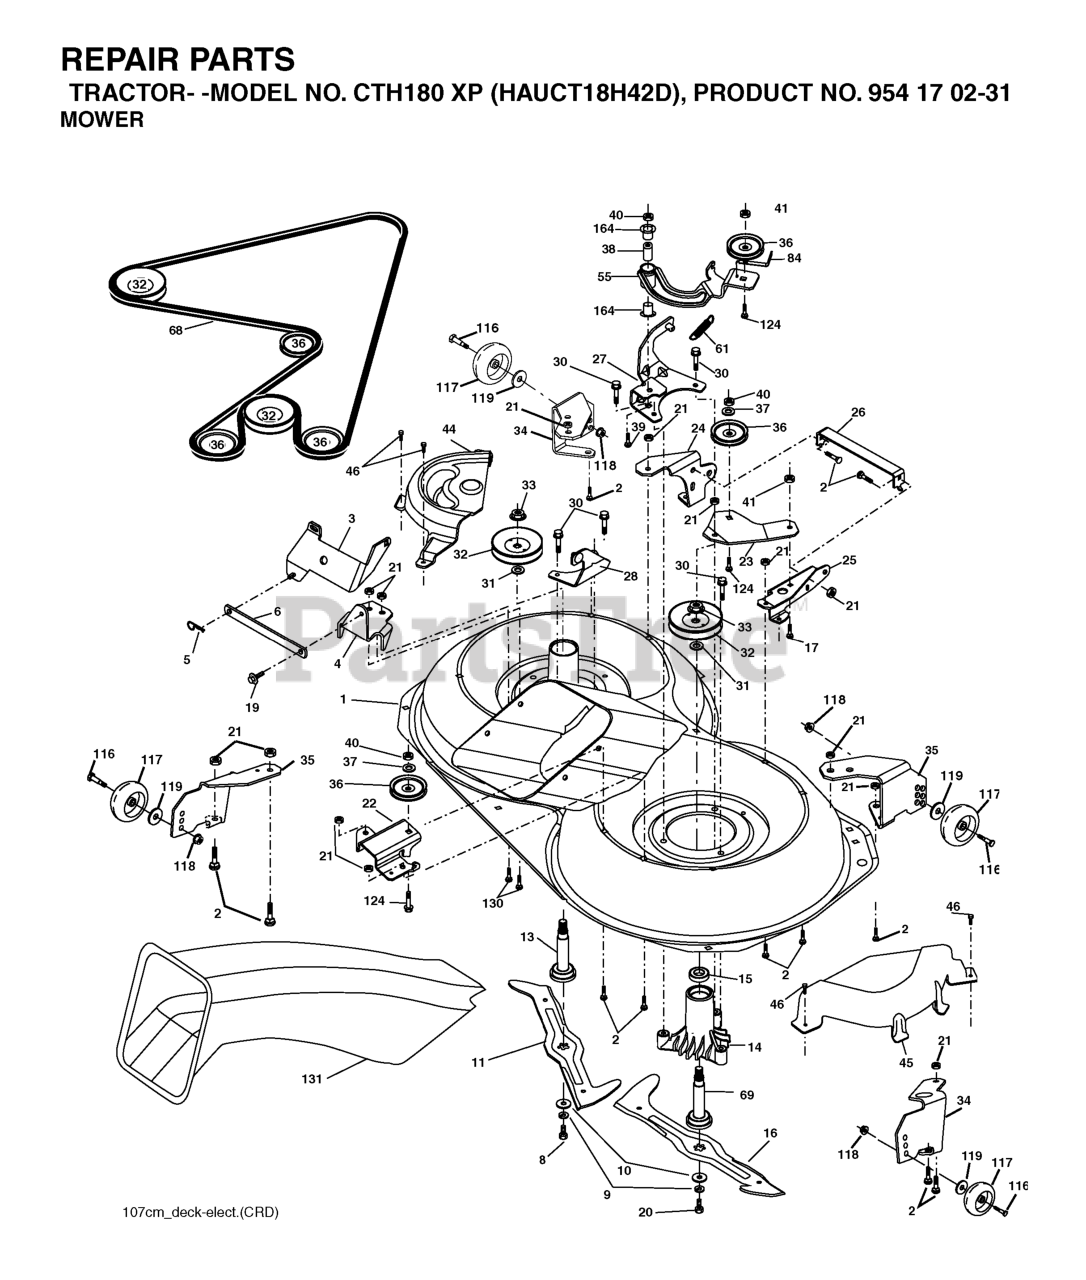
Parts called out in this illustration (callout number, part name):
1	Housing Asm. Mower 107 CRD
2	RP BOLT 5/16-18 X3/4 ZN/YEL GR
5	RETAINER-SPRNG RB
6	BAR.SWAY.92.CRD
8	BOLT.3/8-24X1.25 GR8
9	LOCKWASHER
10	WASHER.BLADE
11	BLADE.3N1.LH.CRD
13	SHAFT ASM VENT
14	HOUSING.MANDREL.VENTED (MACHD)
16	BLADE.3N1.RH.CRD
19	BOLT SHD 5/16-18
20	BOLT.3/8-24X1.25GR8. LHTHRD
21	LOCKNUT
22	BRACKET.IDLER.RR.107.CRD
25	BRACKET.SUSPENSION.RF.107.CRD
26	BRACE.SUPT.SUSP.FRT.CRD
28	BRACKET
30	SCREW, WASHER HEAD
31	WASHER.SPACER.MANDREL
33	NUT, FLG TOPLOCK 9/16"
36	PULLEY.IDLER.4.25
41	NUT LOCK FLG 3/8-16 UNC
45	COVER.MANDREL.RH.CRD
46	SCREW.1/4-20X5/8
55	ARM.IDLER.107.CRD
68	HEX-BELT 107 MOWER
69	SHAFT.ASM.W/LWR.BRG.RH.THREAD
84	KEEPER, BELT IDLER
116	SHOULDER BOLT
117	WHEEL GAGE DONUT
118	LOCKNUT
119	WASHER.5/16.FLAT.STE.STD.
124	BOLT.3/8-16X1.50
130	BOLT.CARR.SQNK.5/16-18UNC.X3/4
131	CHUTE BAGGER
164	BRNG T
